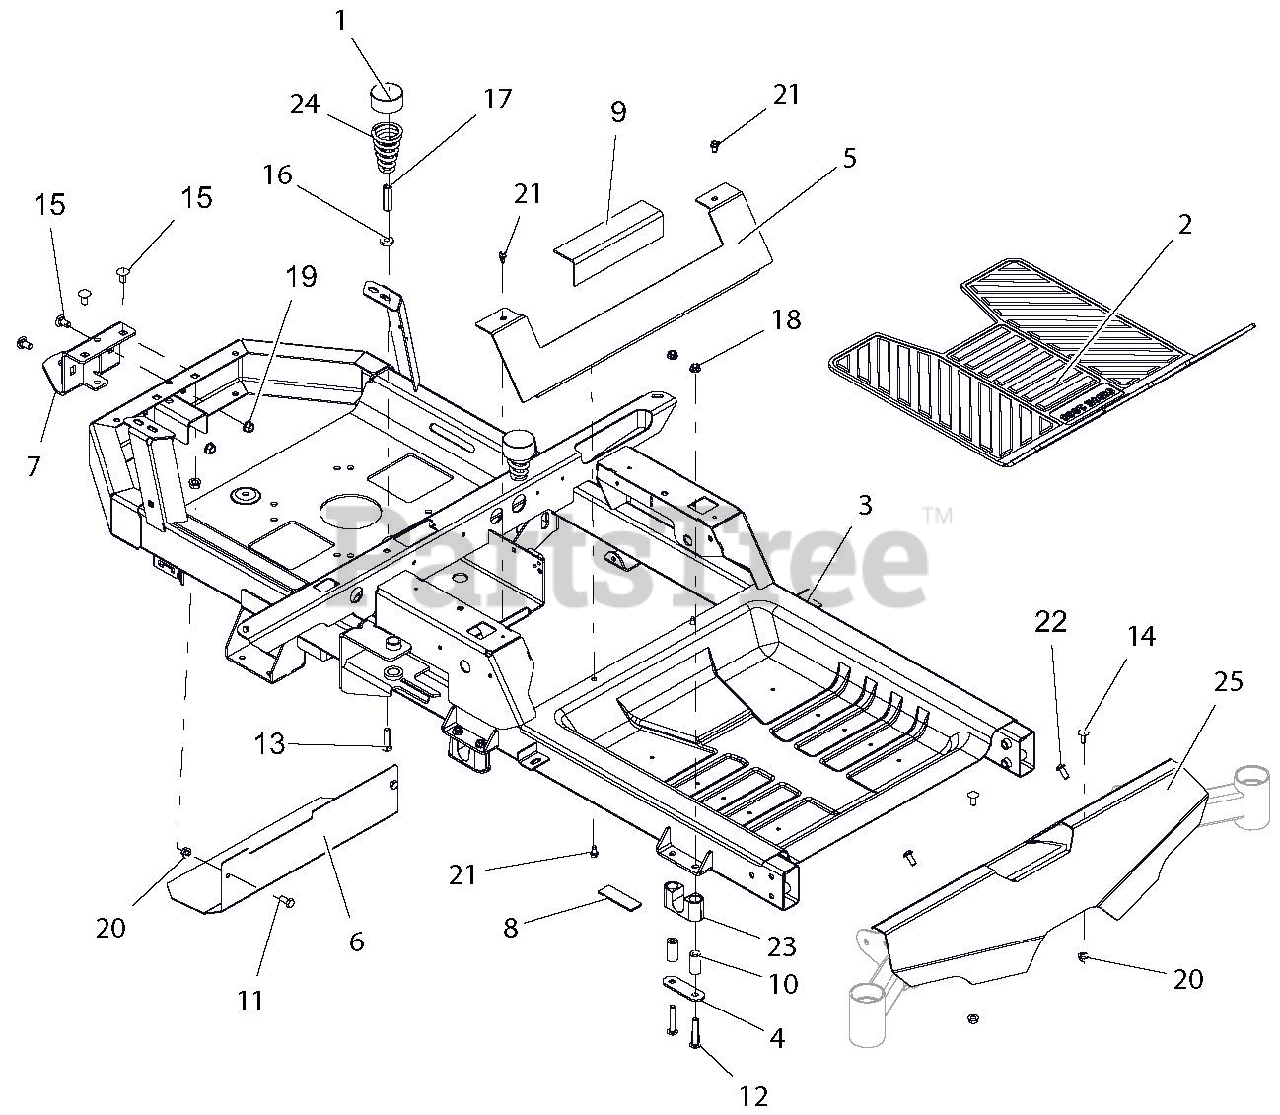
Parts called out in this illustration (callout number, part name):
1	HUB CAP
2	FLOOR MAT, RUBBER - ARIENS
3	WLDMT, FRAME - 2015 ZOOM
4	PLATE, BEARING SUPPORT
5	PLATE, SEAT KICK
6	HEAT, SHIELD
7	BRKT, HITCH TONGUE
8	PAD,RBR 1.0"X3.0" W/ADHESIVE
9	PAD, RUBBER-TANK
10	SPACER, .323 X .698 X 1.441
11	@BLT-HEX .31-18X.75 GR5 YWZC
12	BLT-RDHDSQSHNK .31-18 X 2.00
13	@BLT-RDHDSQNK .31-18X1.50 G5YZ
14	@BLT-RDHDSQNK .31-18X.75 G5YZ
15	@BLT-RDHDSQNK .38-16X.75 G5YZ
16	WSHR-FL-STL .328X.87X.179 YWZC
17	NUT, COUPLING 5/16-18 X 1 3/4
18	@NUT-LK-CTR-FLG .31-18 YZ GR F
19	@NUT-LK-TOP-FLG .38-16 YWZC
20	@NUT-LK-TOP-FLG .31-18 YWZC
21	SCR-TAP .25-20X.50 HWH TR YWZ
22	SCR-RDHDSKTAP .31-18 X .75
23	BSHG, DECK LIFT PIVOT
24	SPRING, SEAT
25	KIT, FOOTPLATE W/DECAL -IKON
